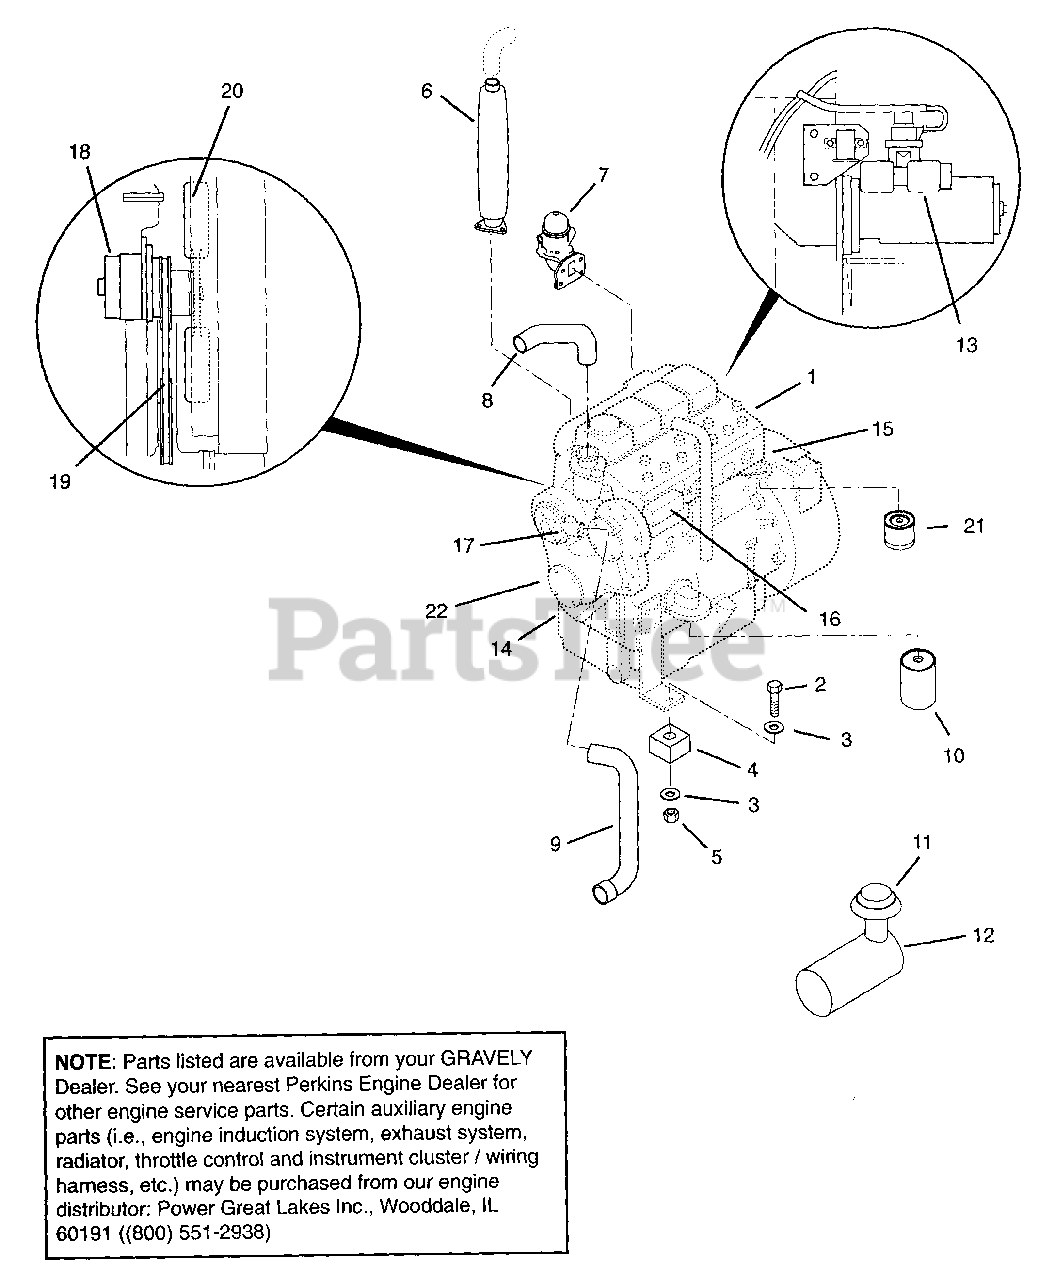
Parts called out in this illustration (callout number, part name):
1	Engine-Perkins 4.236 81 HP
1	Engine-Perkins T4.236 99 HP
1	Engine-Perkins Fastram 108 HP
2	Bolt-Hex .75-10 x 3.00 Grade 5
3	Washer-Flat-Steel .813 x 2.000 x .148
4	Engine Base Spacer
5	Nut-Locking-Center .75-10
6	Muffler
7	Pump-Lift
8	Hose-Radiator-Top
9	Hose-Radiator-Bottom
10	Filter-Oil
11	Filter-Air-Primary
12	Filter-Air-Secondary
13	Starter
14	Gasket Kit-Bottom
15	Gasket Kit-Top
16	Pump-Injection
17	Pump-Water
18	Alternator
19	Belt
20	Fan
21	Element-Fuel Filter
22	Pump-Oil
